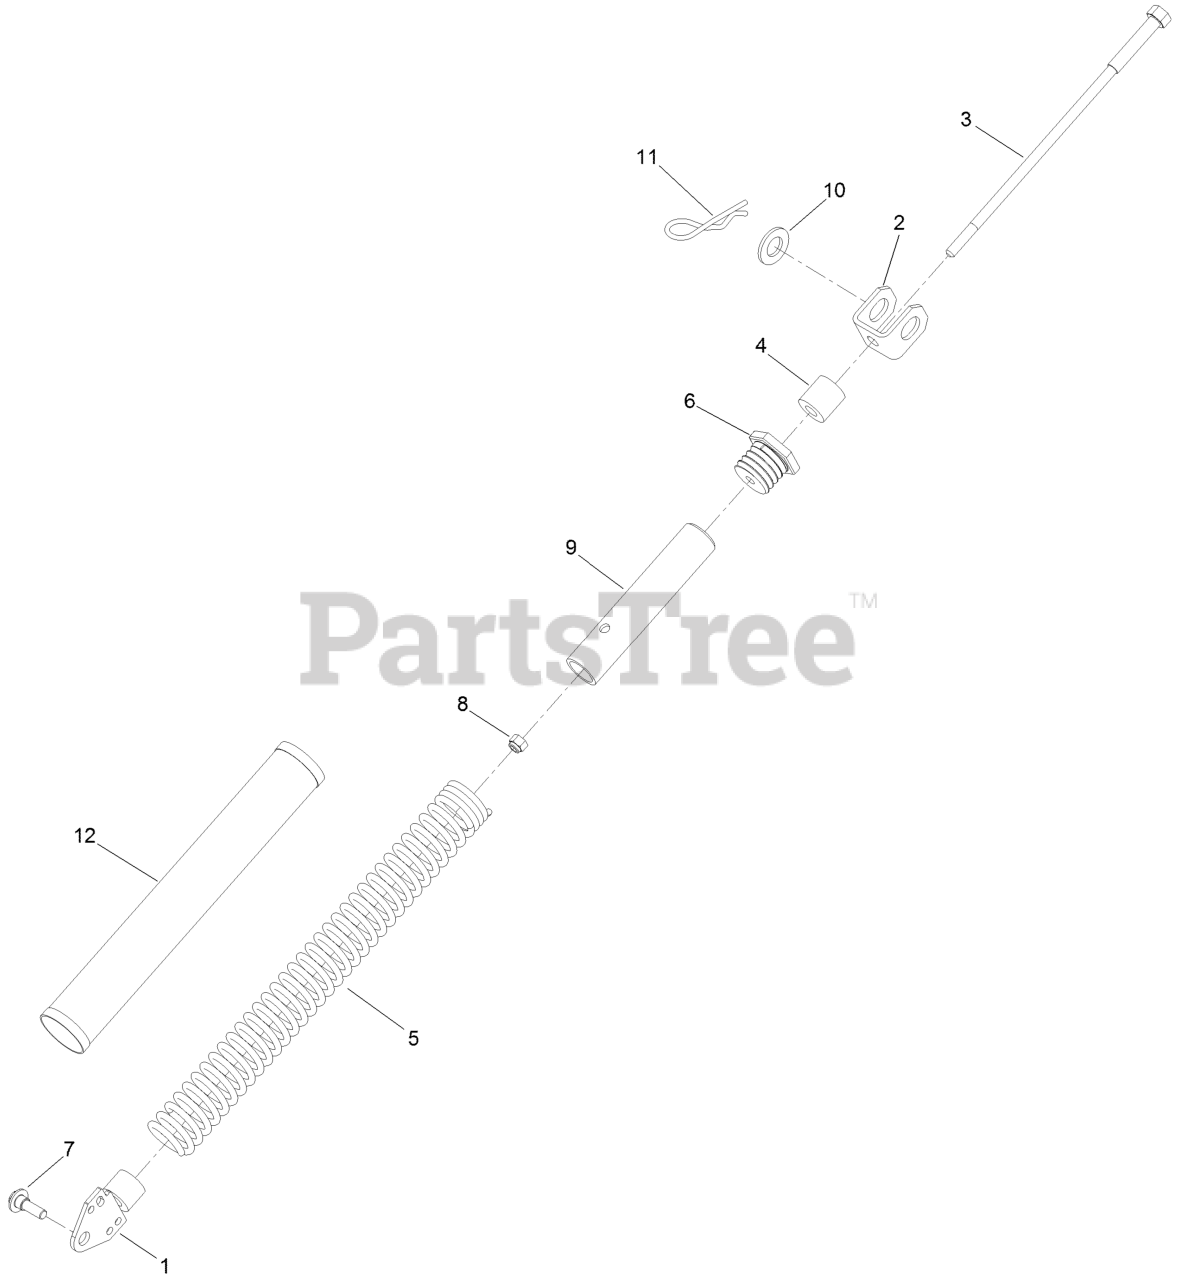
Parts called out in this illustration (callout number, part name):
1	TENSIONER-SPRING
2	MOUNT-LIFT ASSIST, DECK
3	SHAFT-ADJUSTMENT, SPRING
4	SPACER (PLATED)
5	SPRING-EXTENSION
6	PLUG-ADJUSTER, SPRING
7	SCREW-SHOULDER, HWH
8	NUT-LOCK, NI
9	SPRING-TUBE
10	WASHER-FLAT
11	PIN-CUT HEIGHT
12	COVER-SPRING, DECK
